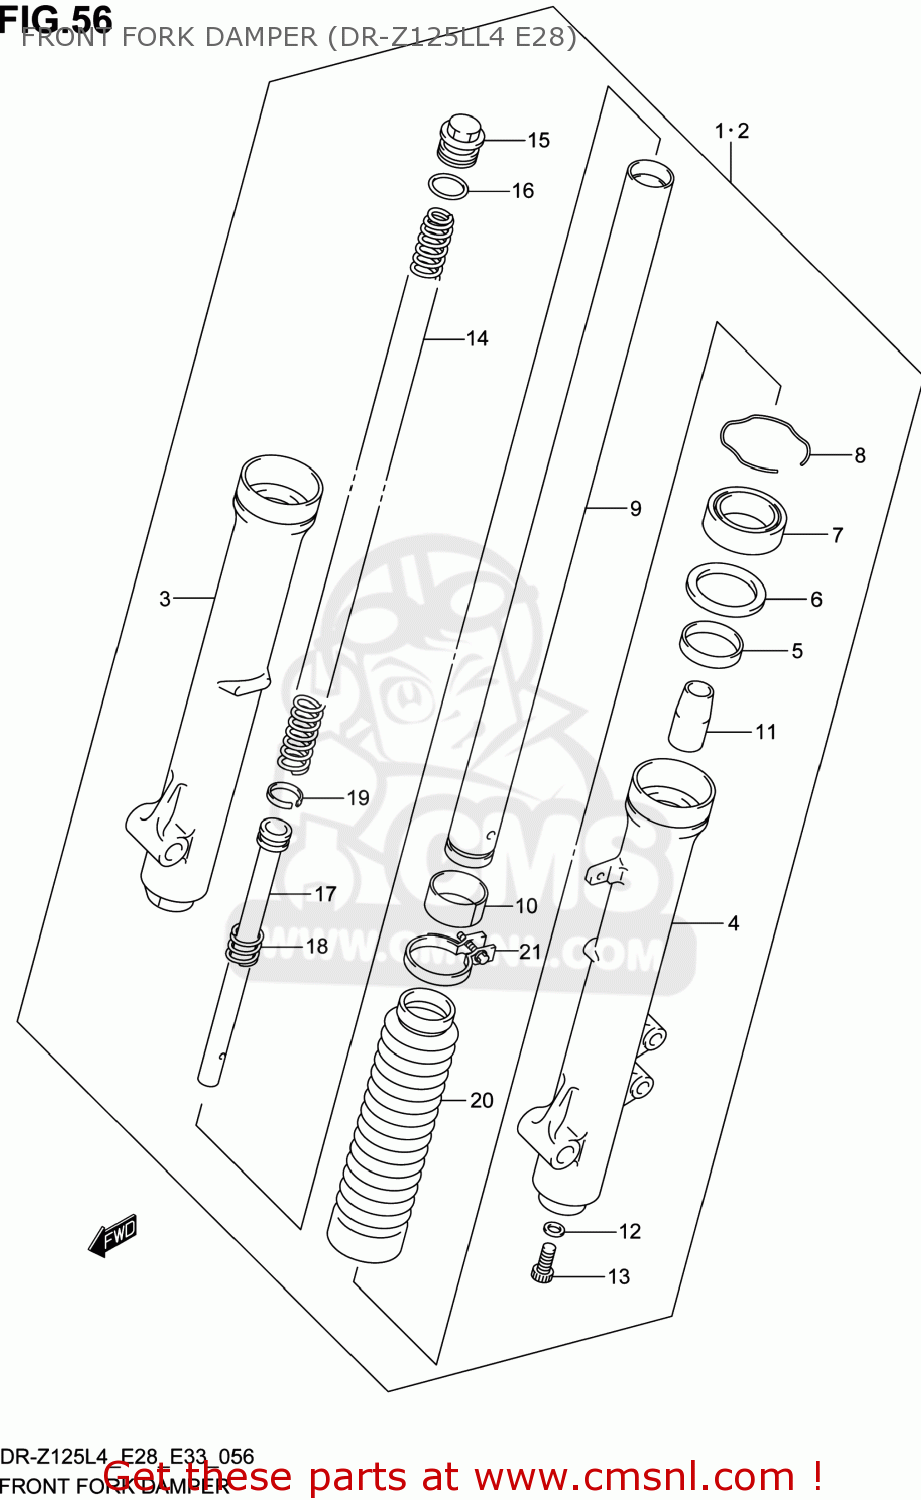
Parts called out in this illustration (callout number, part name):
1	DAMPER ASSY,FR FORK,R
2	DAMPER ASSY,FR FORK,L
3	TUBE,OUTER,R
4	TUBE,OUTER,L
5	BUSH,GUIDE
6	SPACER,SEAL
7	SEAL,OIL
8	SEAL,OIL STOPPER RING
9	TUBE,INNER
10	BUSH,SLIDE
11	PIECE,OIL LOCK
12	GASKET (NAS)
13	BOLT(8X27)
14	SPRING,FR
15	BOLT
16	O RING
17	CYLINDER
18	SPRING,REBOUND
19	RING
20	BOOT
21	BAND
